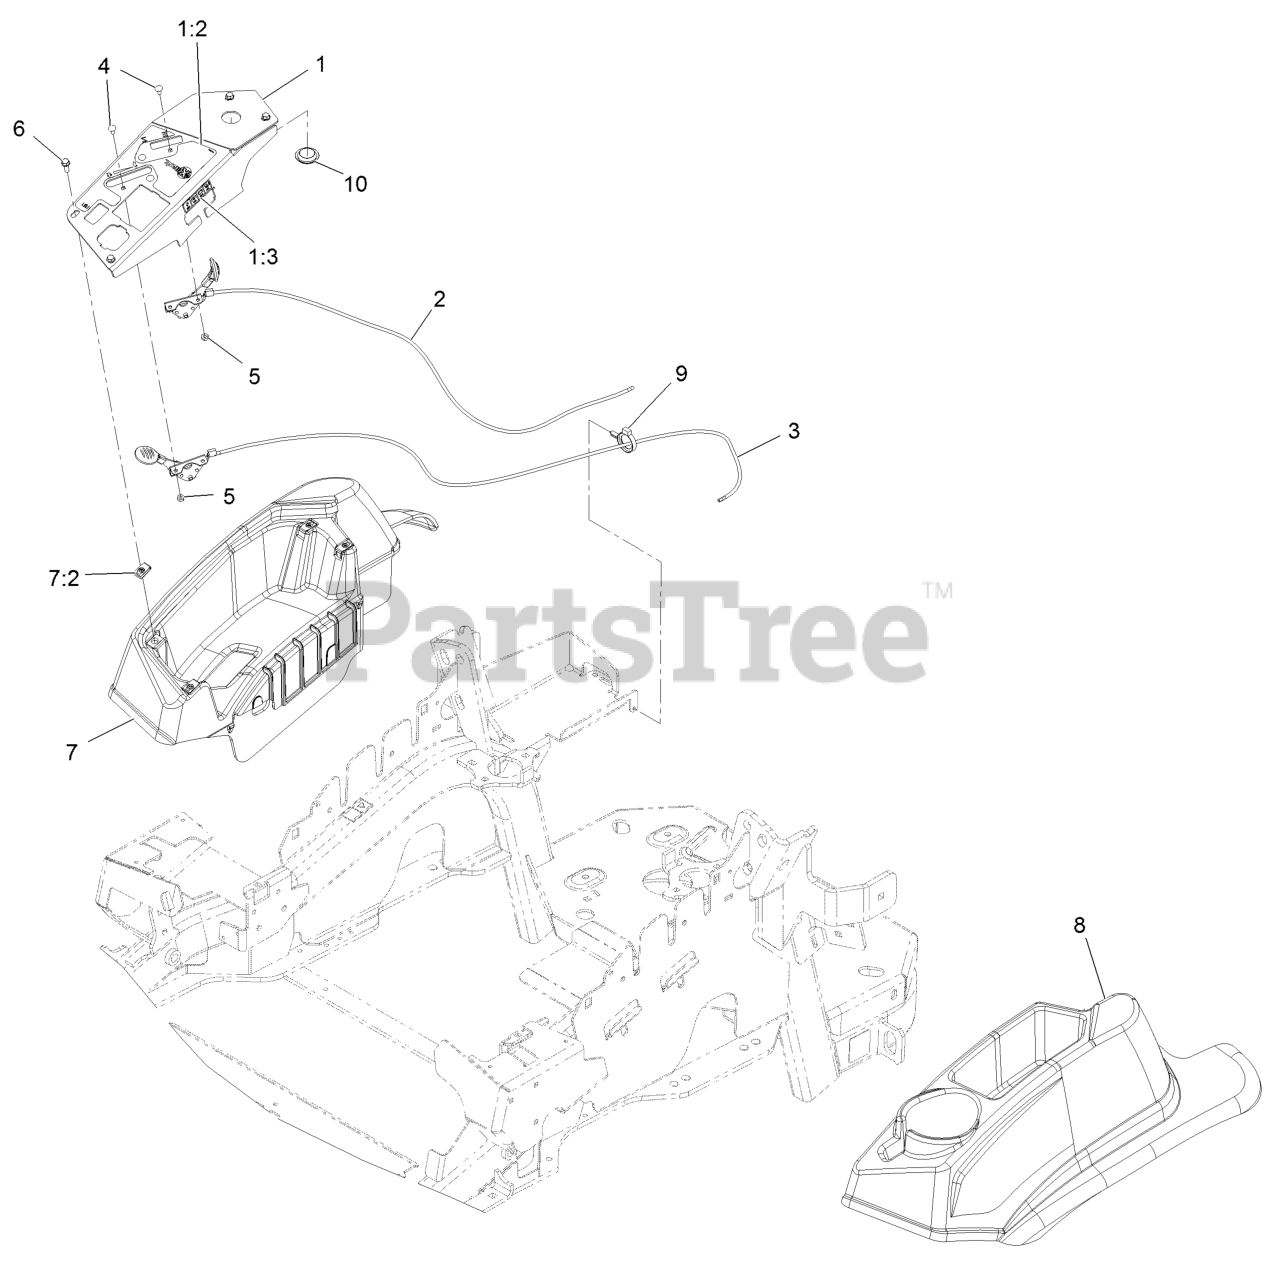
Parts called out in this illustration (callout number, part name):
1	ASM,CONSOLE PANEL W/DECAL
1:2	DECAL-CONTROL PANEL NON-E
1:3	DECAL-FUSES
2	ASM, CHOKE CABLE
3	ASM,THROTTLE CABLE
4	BOLT-CARR
5	NUT-LOCK, NI
6	SCREW-HWH
7	CONSOLE,RH AS ASM
7:2	Nut-Retainer-Panel 1/4-20
8	CONSOLE, LH AS
9	CLAMP-HOSE
10	PLUG-PLASTIC
